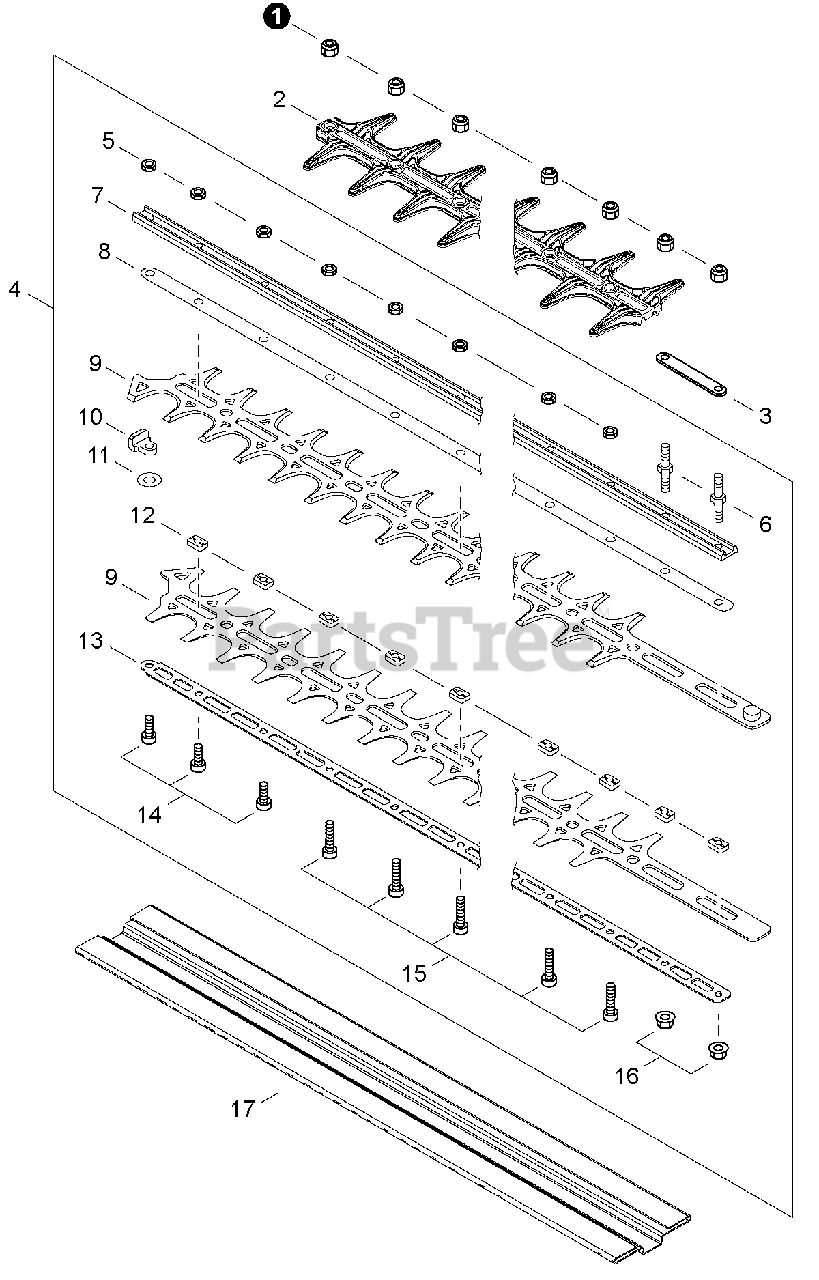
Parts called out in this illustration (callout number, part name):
1	NUT - 5
2	SUPPORT, BLADE
4	BLADE ASSY - 24" (60cm)
7	SUPPORT, CUTTER - 24" (60cm)
8	SUPPORT, CUTTER - 24" (60cm)
9	BLADE - 24" (60cm)
13	SUPPORT, CUTTER - 24" (60cm)
14	SCREW - 5X16
15	SCREW - 5X25
16	NUT - 5
17	COVER, BLADE
